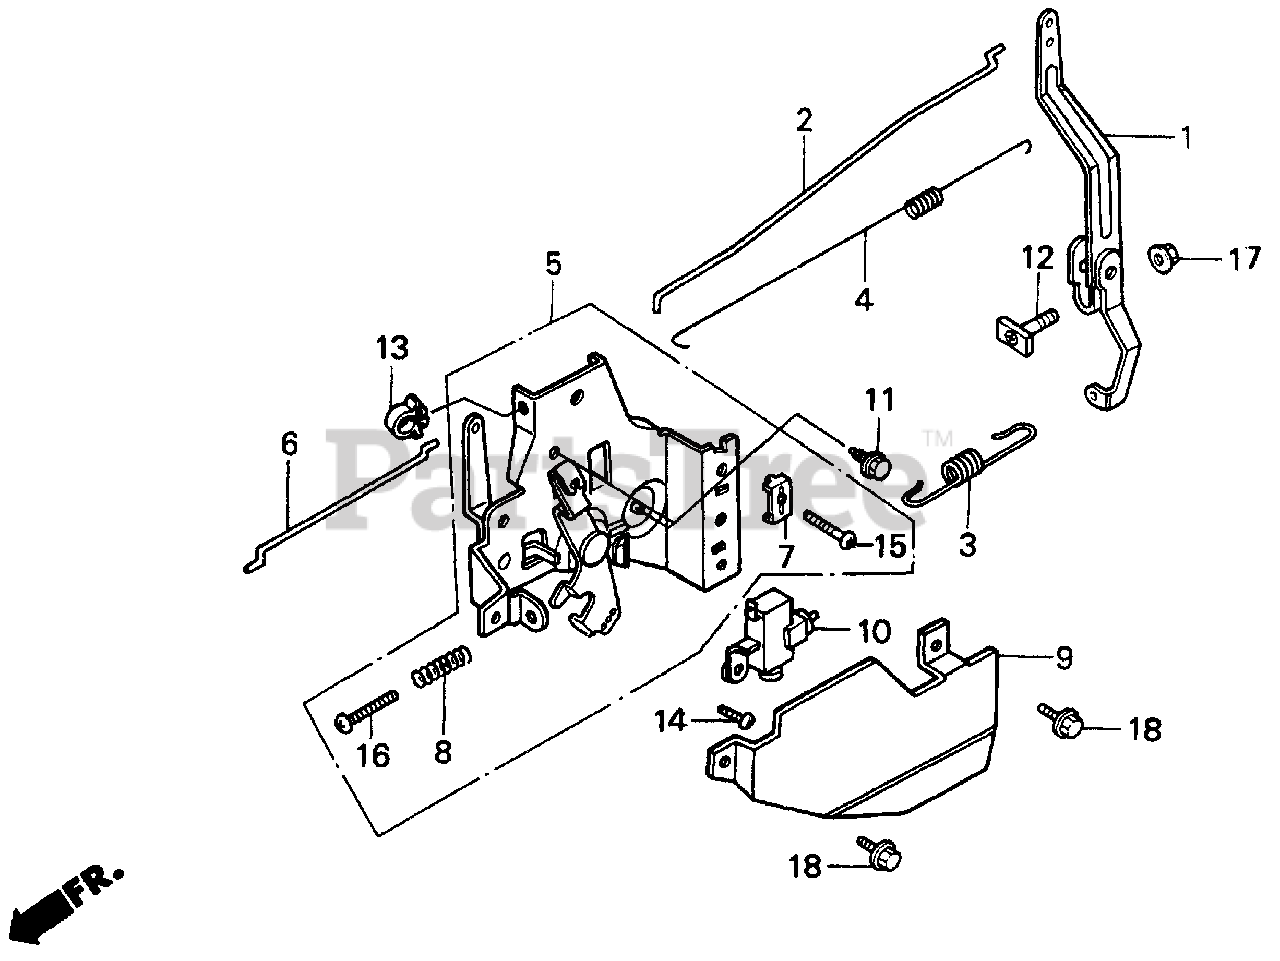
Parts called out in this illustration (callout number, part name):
1	ARM, GOVERNOR
2	ROD, GOVERNOR
3	SPRING, GOVERNOR (STD)
4	SPRING, THROTTLE RETURN
5	CONTROL ASSY.
5	CONTROL
6	ROD, CHOKE
7	HOLDER, CABLE
8	SPRING, CONTROL ADJUSTING Use from Engine SN 2327377.
9	PROTECTOR, CONTROL
10	SWITCH ASSY., ENGINE STOP
11	BOLT, FLANGE (6X12) (CT200)
12	BOLT, GOVERNOR ARM
13	CLIP, WIRE HARNESS
14	SCREW, PAN (4X8)
15	SCREW, PAN (5X16)
16	SCREW, PAN (5X20)
17	NUT, FLANGE (6MM)
18	BOLT, FLANGE (6X10)
